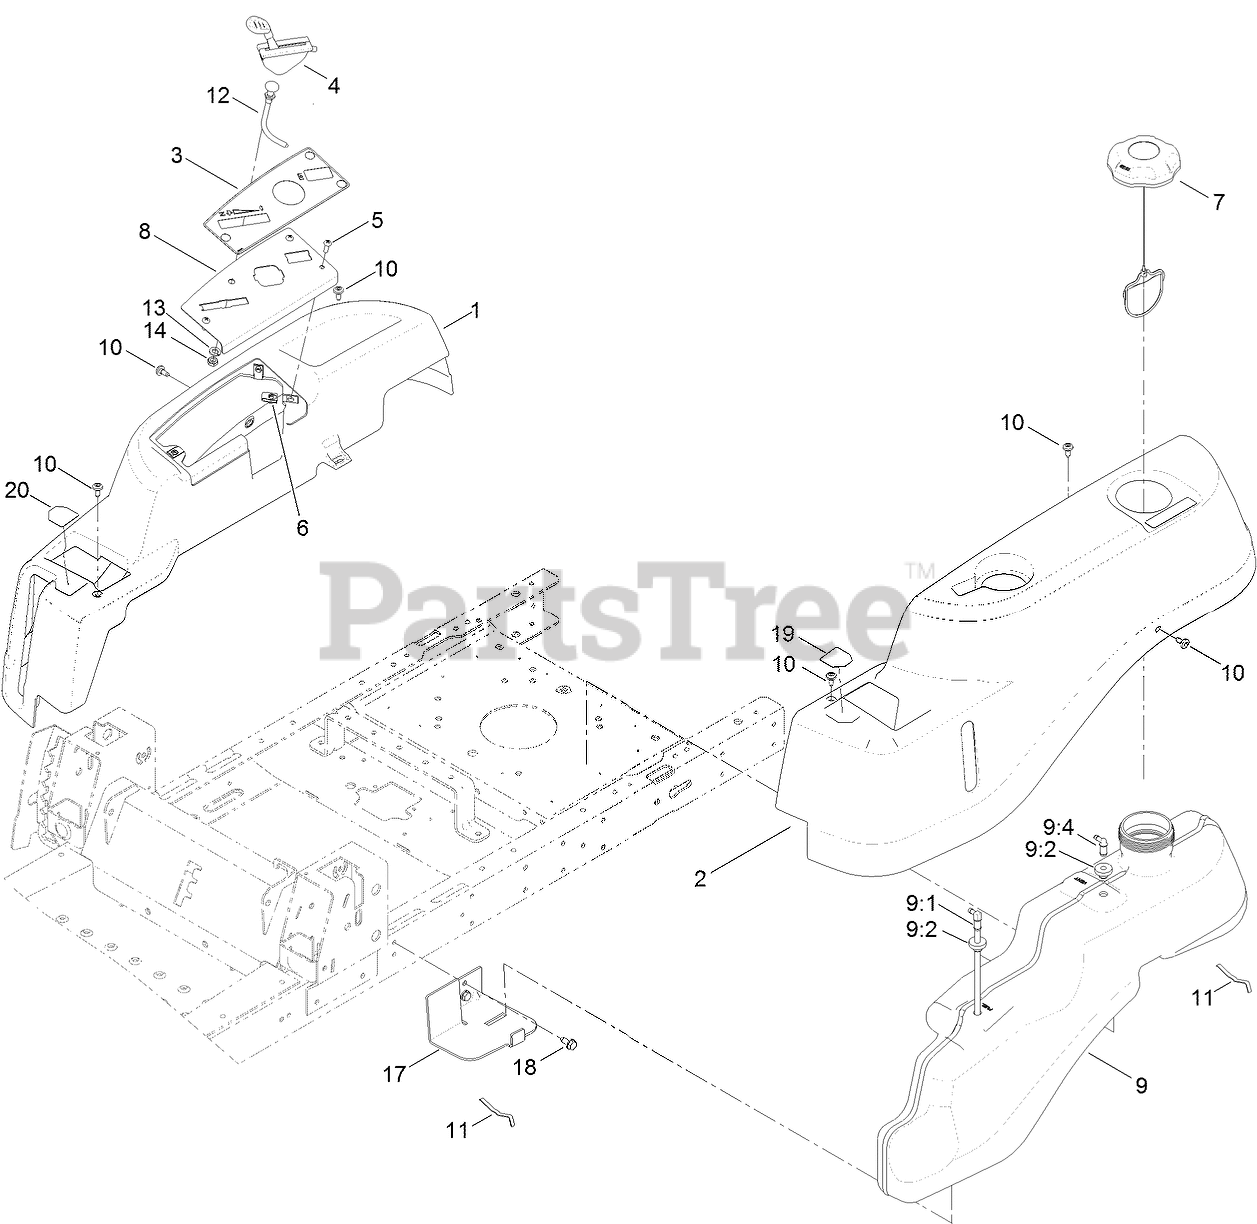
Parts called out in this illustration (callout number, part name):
1	POD-RH
2	POD-LH
3	DECAL-PANEL, CONTROL
4	CABLE-THROTTLE
5	SCREW-PRH
7	CAP-FUEL, RATCHETING
8	PLATE-CONTROL
9	FUEL TANK ASM
9:1	CONNECTOR-ELBOW, 90 DEG
9:2	BUSHING
9:4	FITTING-PLASTIC
10	SCREW-SHOULDER
11	SPRING
12	CABLE-CHOKE
13	WASHER-LOCK
14	NUT-HJ
17	SUPPORT-TANK, FRONT
18	SCREW-HWHTF
19	DECAL-CONTROL LEVER, LH
20	DECAL-CONTROL LEVER, RH
